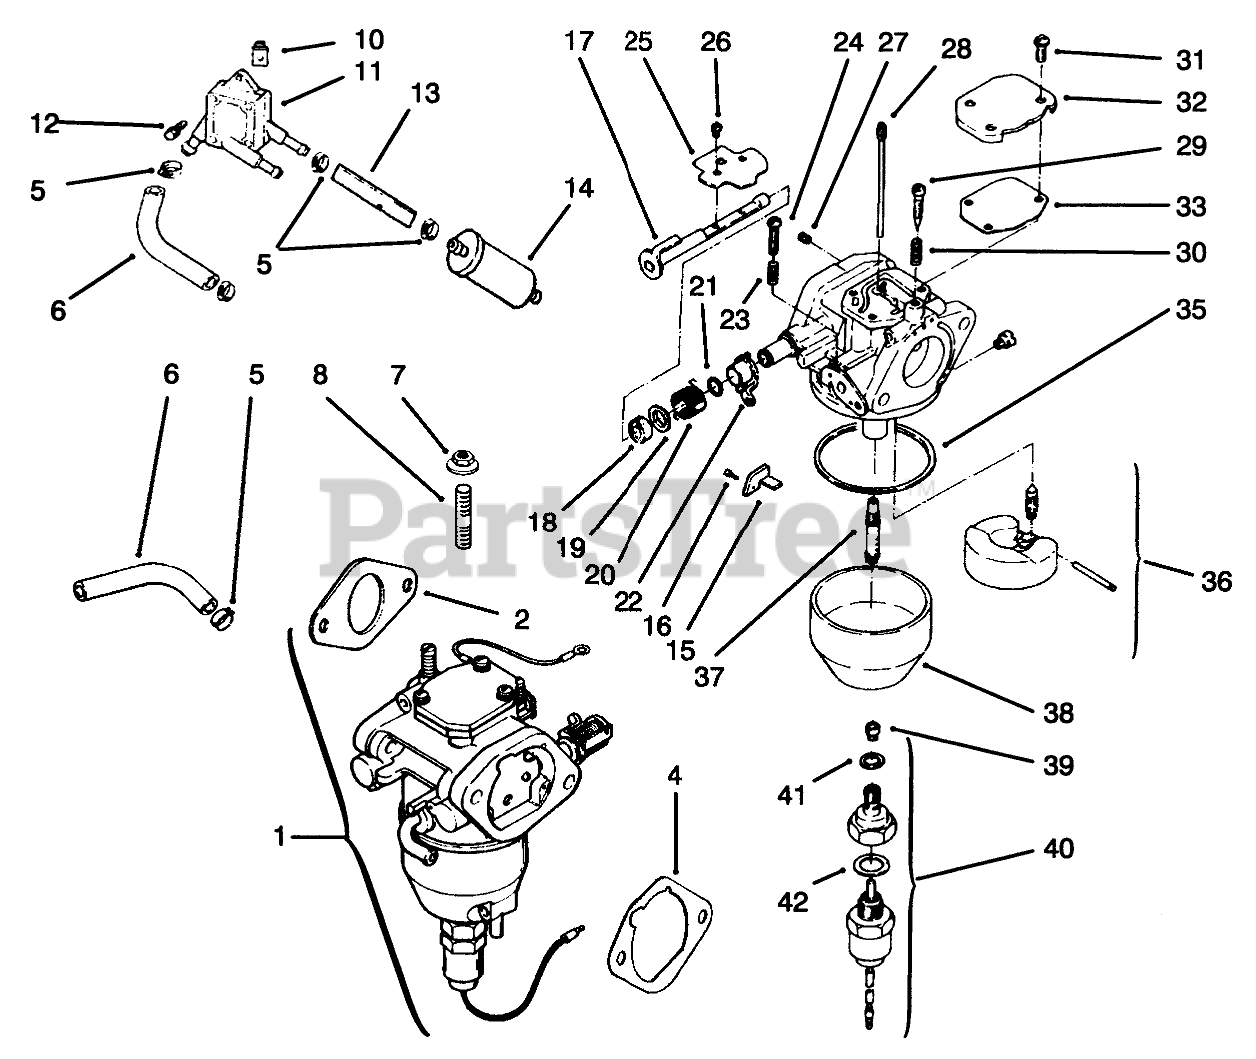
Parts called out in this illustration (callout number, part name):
2	Kit-Carburetor
4	Gasket-A/C Base
5	Clamp
6	Line-Fuel
7	Nut
10	Nut
11	Pump-Fuel
12	Screw
13	Line-Fuel
14	Filter-Fuel
15	Bracket-Throttle Stop
16	Screw
17	Shaft-Choke
18	Washer
19	Collar-Coke
20	Spring-Choke Return
21	Ring-Choke Lever
22	Lever-Choke
23	Sprin-Throttle Screw
24	Screw-Throttle Adjust
25	Valve-Choke
26	Screw
27	Jet-Air Bleed
28	Jet-Slow
29	Screw
30	Spring-idler Screw
31	Screw
32	Cover-Passage
33	Gasket-PassageCover
35	Gasket-FloatChamber
36	Kit-Float Repair
37	Nozzle-Main
38	Chamber-Float
39	Jet-Main
40	Kit-Solenoid INC41-42
41	Gasket-ChamberScrew
42	Gasket-Solenoid
